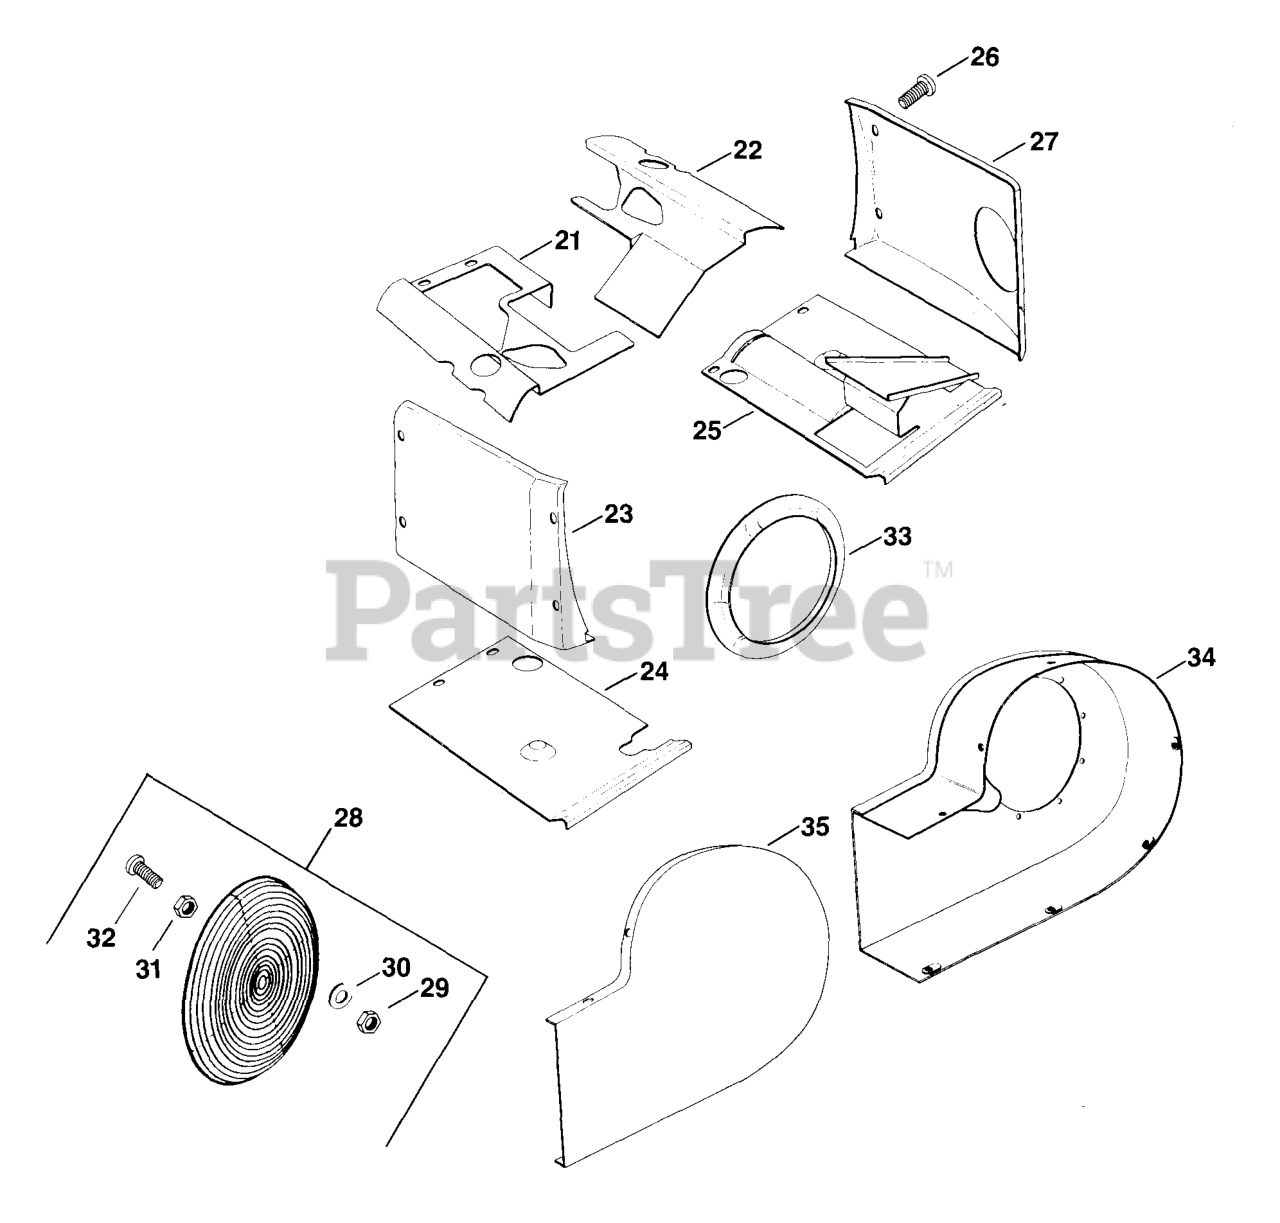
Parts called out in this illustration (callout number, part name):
21	BAFFLE - DISCONTINUED
22	BAFFLE - DISCONTINUED
23	BAFFLE - DISCONTINUED
24	BAFFLE - DISCONTINUED
26	BAFFLE - DISCONTINUED
